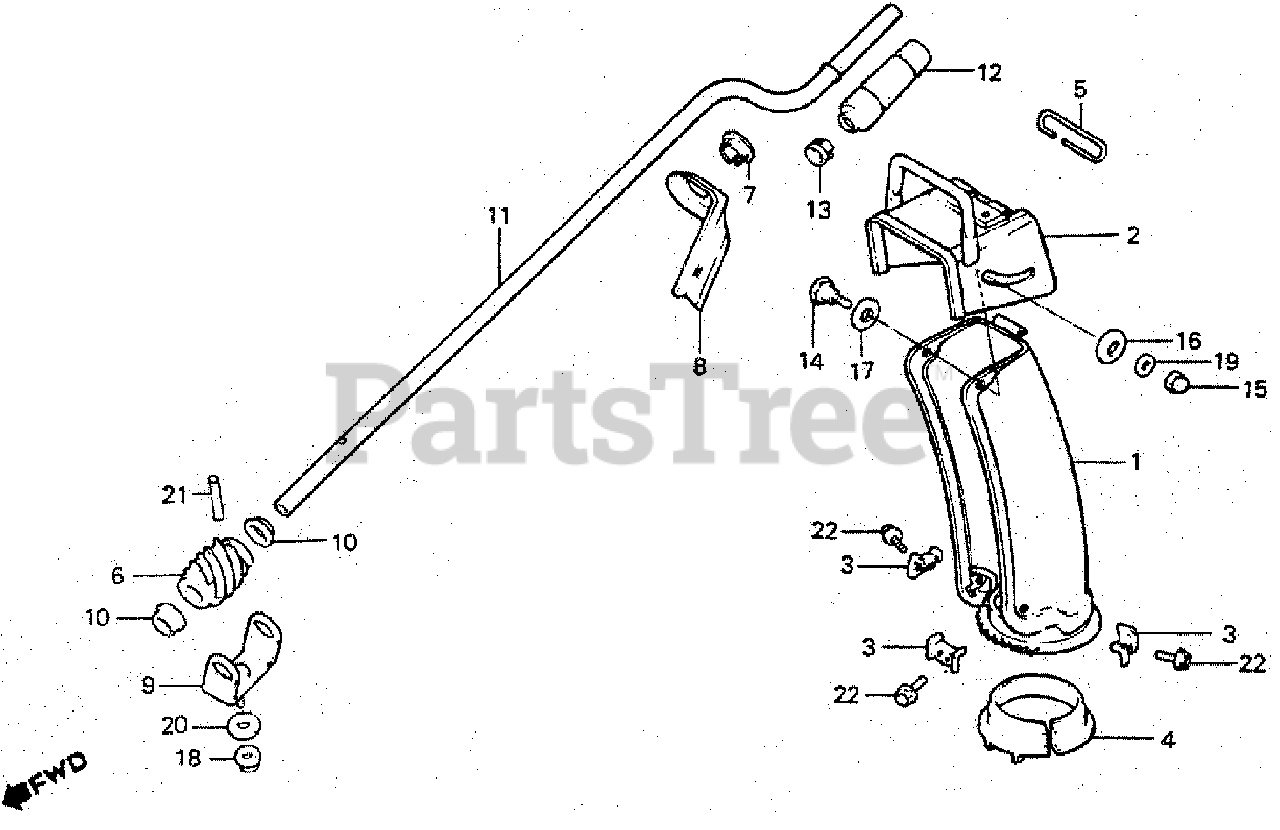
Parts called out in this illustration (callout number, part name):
1	CHUTE (NOT AVAILABLE)
2	GUIDE, CHUTE
3	PLATE, CHUTE SETTING
4	BUSH, CHUTE
5	PIN, CHUTE GUIDE
6	GEAR, CHUTE DRIVE
7	BUSH, CHUTE HANDLE
8	BRACKET, HANDLE
9	STAY, DRIVE GEAR
9	STAY, DRIVE GEAR (NOT AVAILABLE)
10	BUSH, DRIVE GEAR
11	HANDLE, CHUTE (NOT AVAILABLE)
12	GRIP, CHUTE HANDLE
13	BUSH A, CHUTE HANDLE
14	SCREW, PIVOT
15	NUT, CAP (6MM)
16	SPRING, LEVER
17	WASHER, PLAIN (10.3MM)
18	NUT, FLANGE (8MM)
19	WASHER, PLAIN (6MM)
20	WASHER, PLAIN (8MM)
21	PIN, SPRING (4X32)
22	BOLT, FLANGE (6X12)
22	BOLT, FLANGE (6X10)
